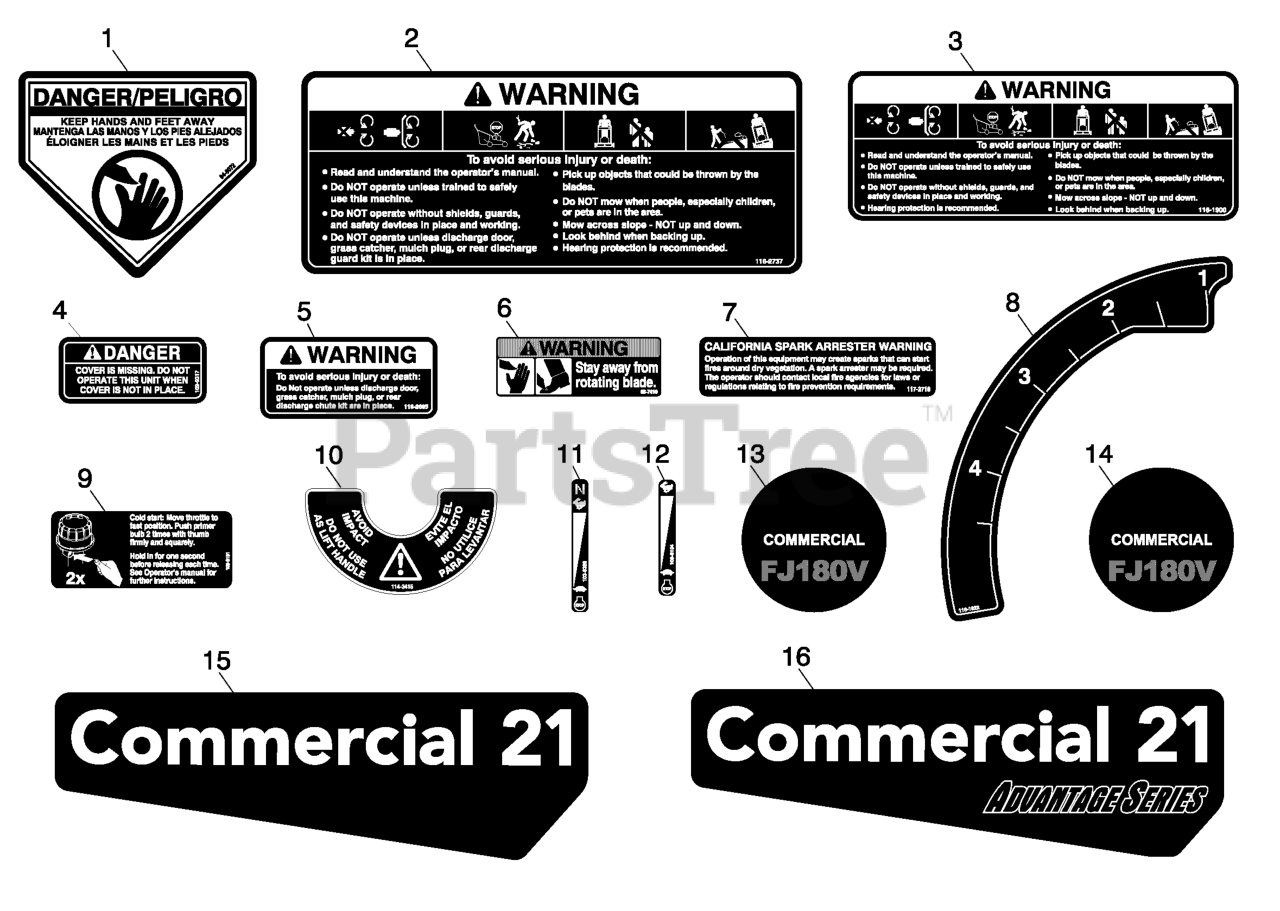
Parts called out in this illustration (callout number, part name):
1	DECAL-DANGER
2	DECAL-WARNING DOOR LG
3	DECAL-WARNING
4	DECAL-COVER MISSING
5	DECAL-WARNING DOOR SM
6	DECAL-BLADE
7	DECAL-ARRESTER, SPARK
8	DECAL-HEIGHT OF CUT
9	DECAL, PRIMER
11	DECAL-THROTTLE / CHOKE
12	DECAL THROTTLE CONTROL BB
14	DECAL-RECOIL
15	DECAL,COMMERCIAL 21
16	DECAL,COMMERCIAL 21 AS
